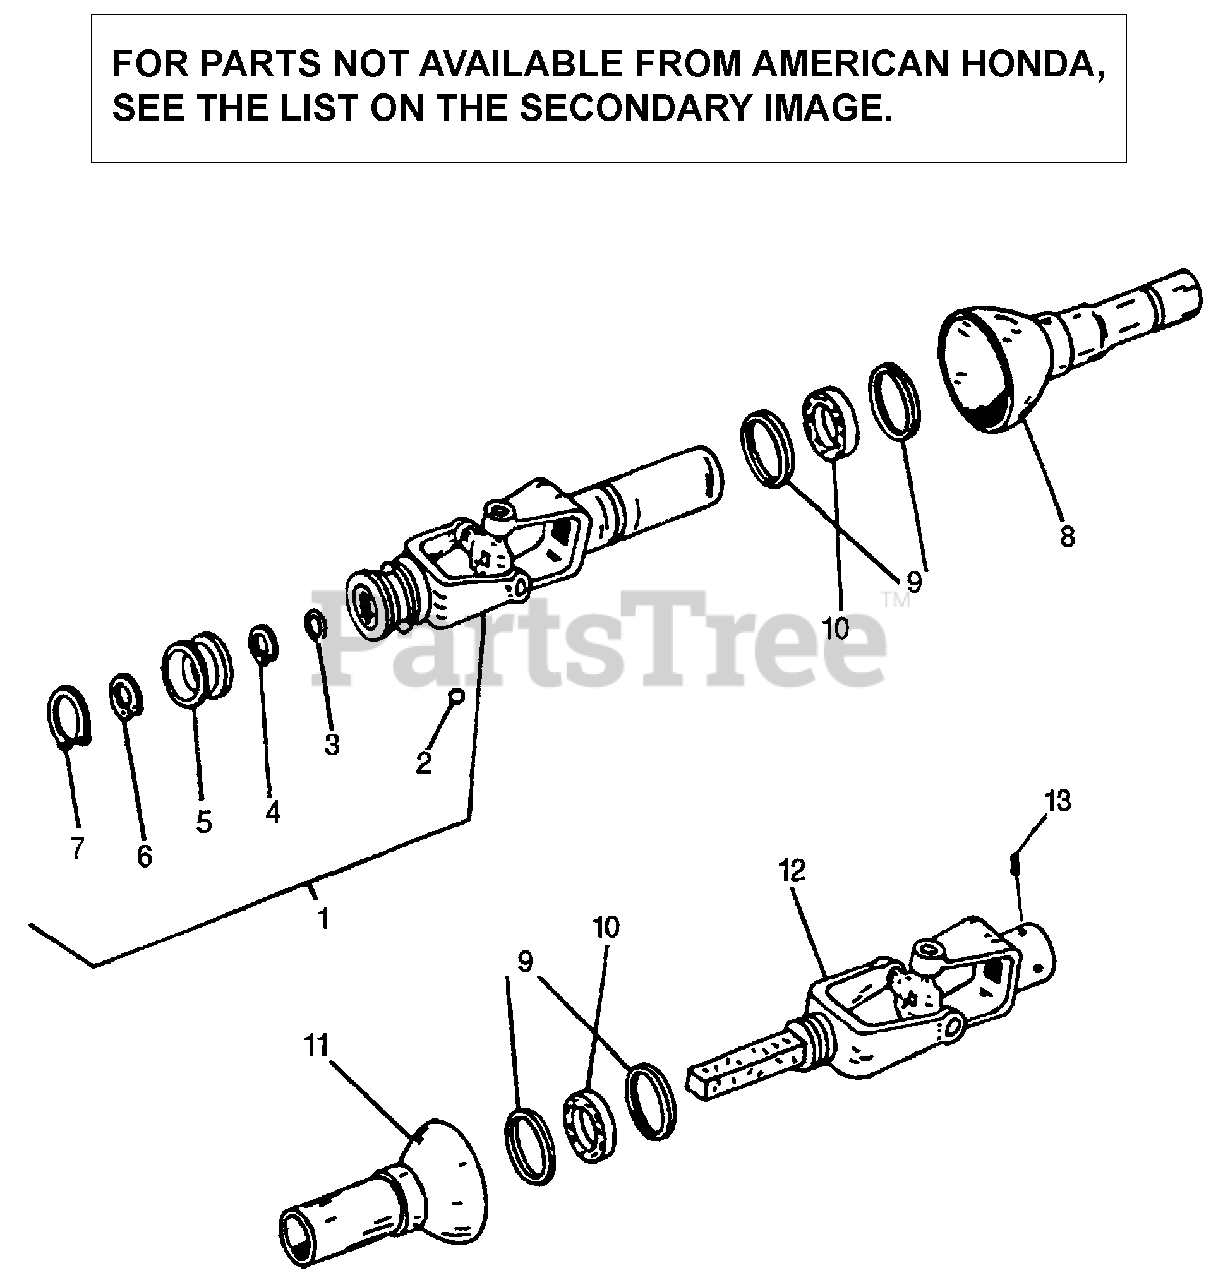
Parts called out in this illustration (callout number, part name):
1	SHAFT ASSY., P.T.O.
2	BALL, STAINLESS (3/8")
4	RING, SPRING RETAINING
6	RING, RETAINING (INNER)
7	RING, RETAINING (OUTER)
9	RETAINER, BEARING
10	BEARING, NYLON
